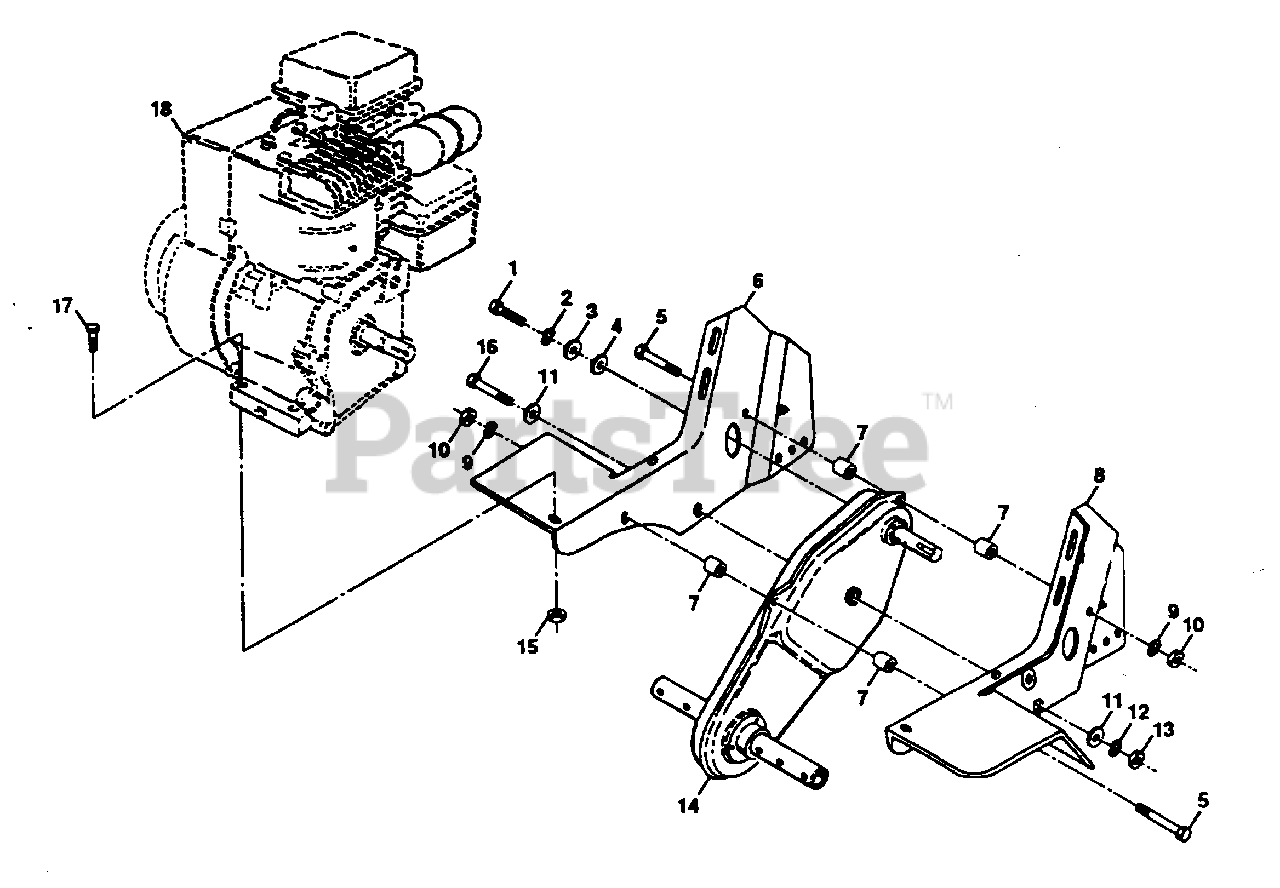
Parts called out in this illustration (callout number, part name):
1	Bolt, Hex 1/4-28 x 3/4 Gr. 5 (AYP part number)
2	Washer, Lock 1/4 (AYP part number)
3	Washer 9/32 x 1-1/4 x 16 Ga. (AYP part number)
4	Washer 9/32 x 7/8 x 12 Ga. (AYP part number)
5	Bolt, Hex 5/16-18 x 2-3/4 (AYP part number)
6	Bracket, Engine, R.H. (AYP part number)
7	Spacer, Split (AYP part number)
8	Bracket, Engine, L.H. (AYP part number)
9	Washer, Lock 5/16 (AYP part number)
10	Nut, Hex 5/16-18 (AYP part number)
11	Washer 13/32 x 13/16 x 11 Ga. (AYP part number)
12	Washer, Lock 3/8 (AYP part number)
13	Nut 3/8-24 (AYP part number)
14	Transmission (AYP part number)
15	Nut, Keps 5/16-18 (AYP part number)
16	Bolt, Hex 3/8-24 x 3-1/4 Gr. 5 (AYP part number)
17	Bolt, Hex 5/16-18 x 1-1/2 (AYP part number)
